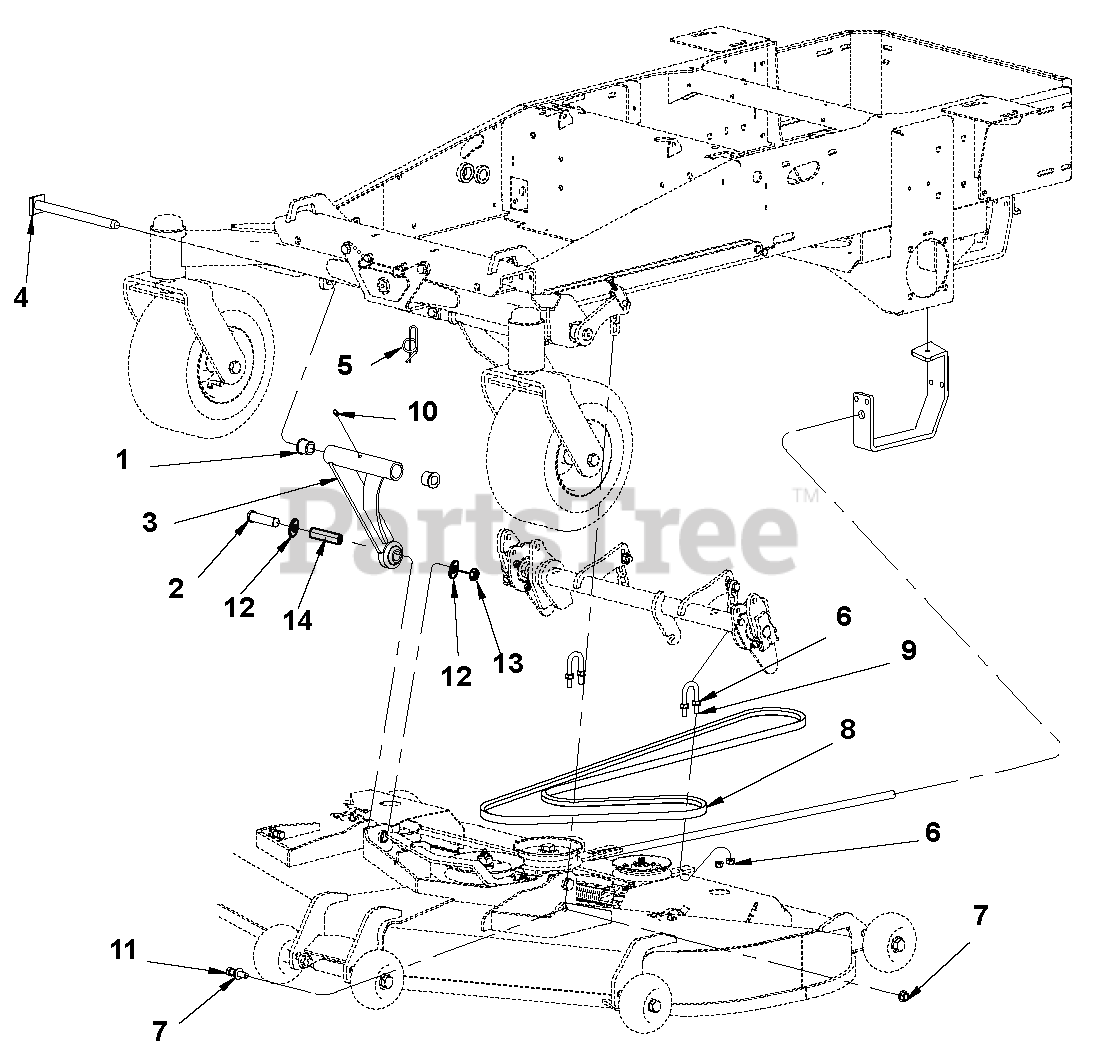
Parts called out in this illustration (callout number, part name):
1	Bushing, 3/4 I.D.
2	Bolt, .50-13 x 3.50 Hex 5
3	Weldment, Deck Pull 11.5
4	Weldment, Drag Link Pin
5	Ring, Rue .750 x .080 x 2.081
6	Locknut, 3/8-16 Whiz
7	Locknut, 7/16-14 Whiz
8	Belt, B112 Kevlar (Clutch to Deck)
9	U-Bolt Special
10	Fitting, 1/4-28 Straight Grease Zerk
11	Bolt, 7/16-14 x 1 3/4 GR5
12	Washer, .500 REG Flat
13	Locknut, 1/2-13 Crown
14	Tube, RD .750 x .125W x 2.469
